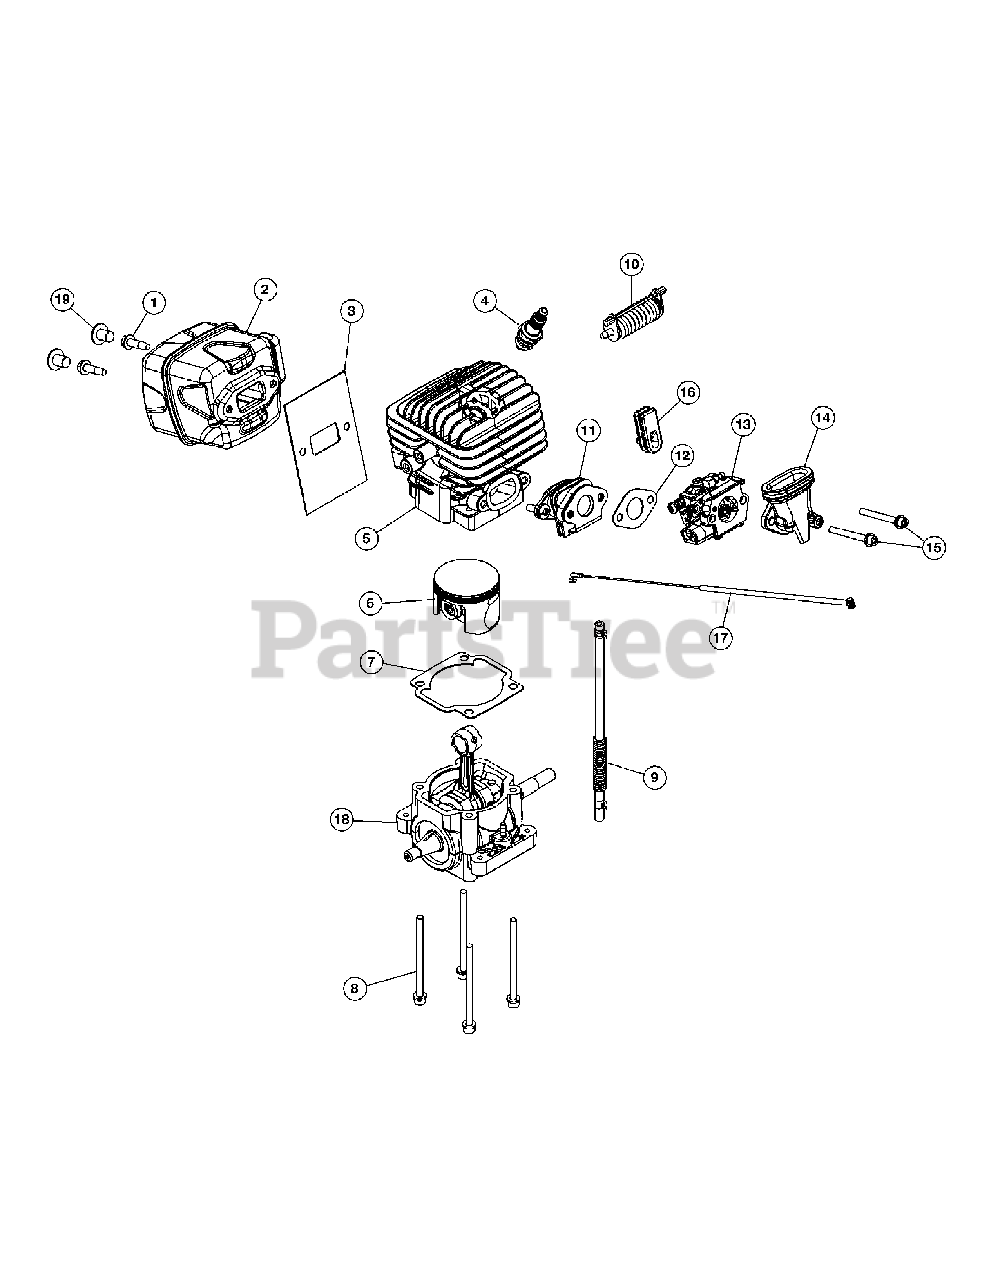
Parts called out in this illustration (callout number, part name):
1	Muffler Screw
2	Muffler Assembly (Incl. 1, 3 & 19)
3	Muffler Gasket
4	Spark Plug
5	Cylinder Assembly
6	Piston Assembly
7	Cylinder Gasket
8	Cylinder Hardware Kit (4 screws)
9	Breather Hose w/clamp
10	Isolator Assembly
11	Insulator Assembly
12	Carburetor Gasket
13	Carburetor
14	Boot & Bracket Assembly
15	Carburetor Hardware Kit (2 screws)
17	Throttle Cable
18	Shortblock Assembly (Incl. 2-10)
19	Muffler Plug
